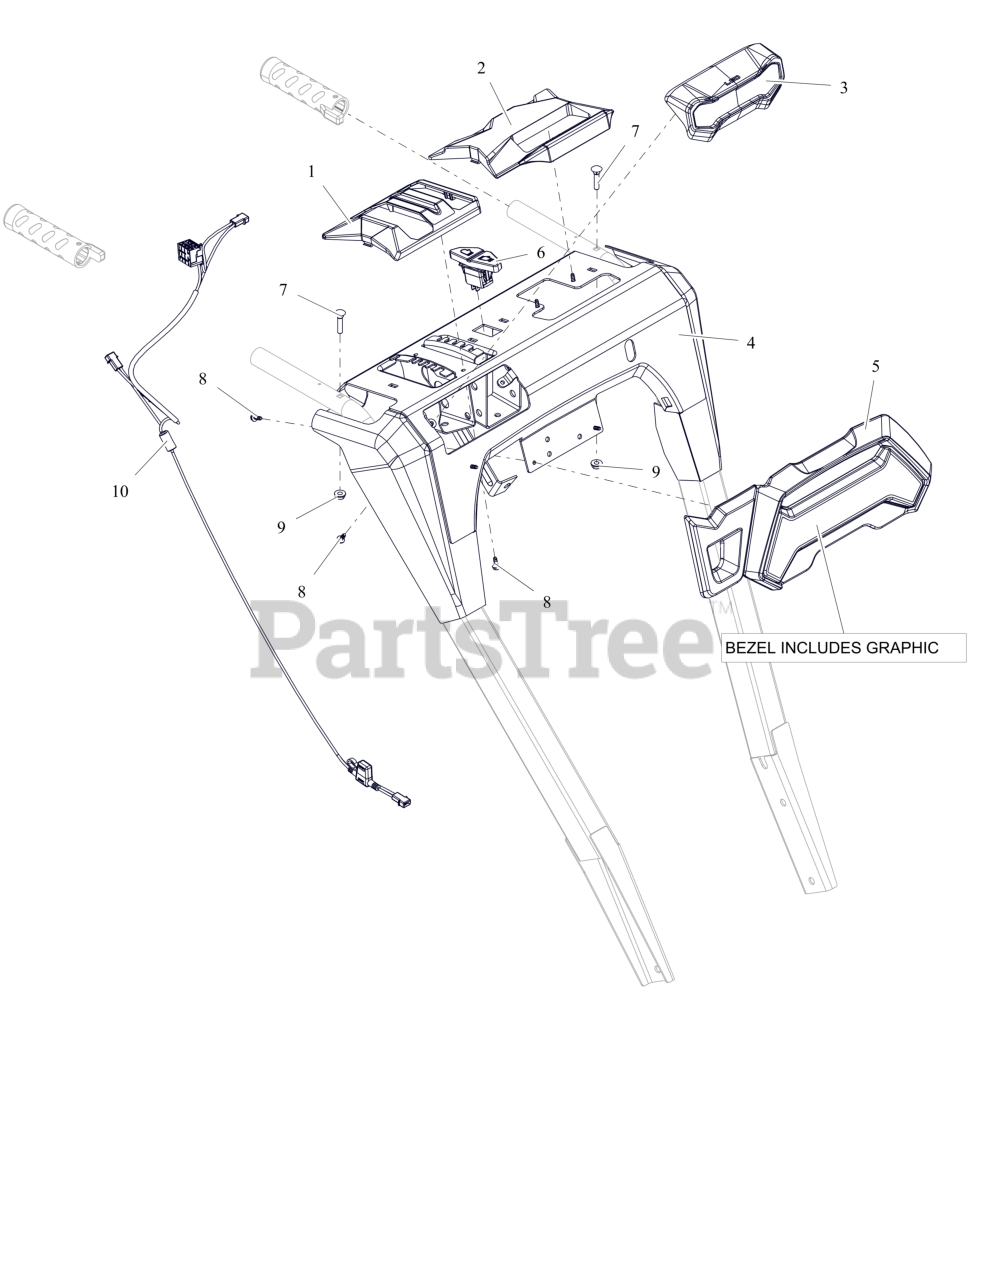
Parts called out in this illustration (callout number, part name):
1	BEZEL, SHIFT - FRICTION
2	BEZEL, OPERATOR CHUTE DECAL
3	HEADLIGHT ASM- LED
4	PANEL, DASH-FRICTION QT W/DECAL
5	BEZEL- LARGE - PROFESSIONAL
6	SWITCH- ROCKER SPST-ON/OFF
7	BLT-RDHDXLSQNK.25-20X1.25 G5ZC
8	SCR, PLASTIC #10X.50
9	NUT-LK-CTR-FLG .25-20 ZC120
10	HARNESS- WIRE - LT HG
